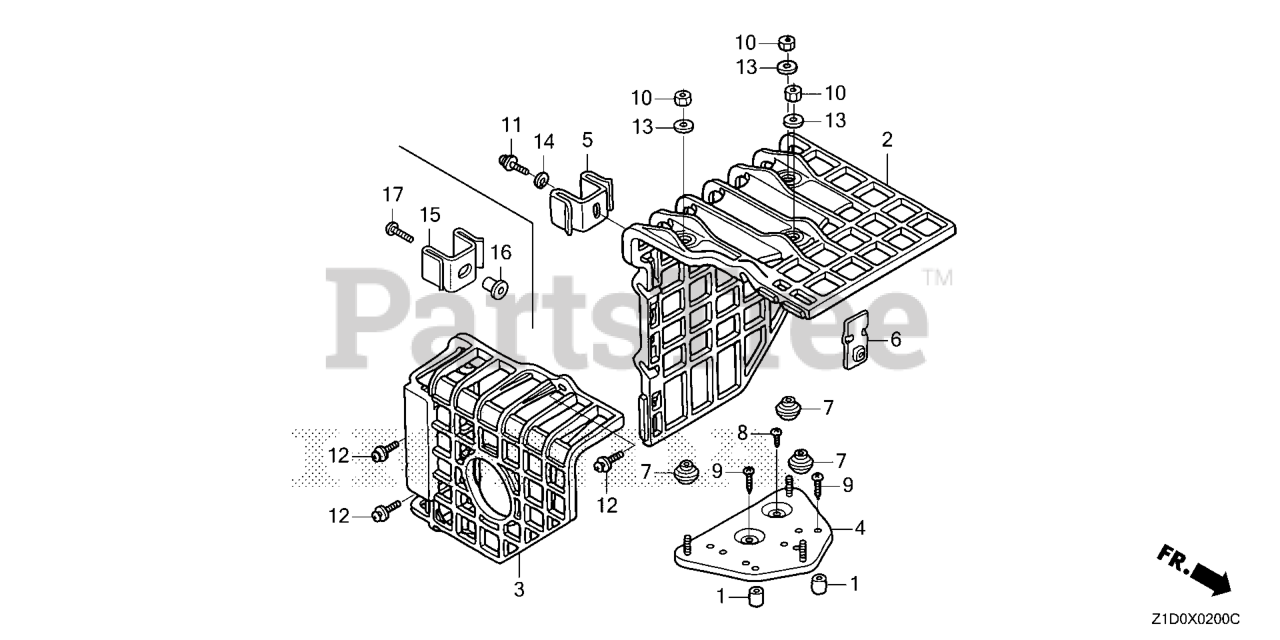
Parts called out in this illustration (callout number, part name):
1	COLLAR, AIR CLEANER HOUSING
2	COVER, MUFFLER
3	COVER, RR. MUFFLER
4	BASE, MUFFLER COVER
7	SPACER, MUFFLER COVER
8	SCREW, TAPPING (5X8)
9	SCREW, TAPPING (5X25)
10	NUT, HEX. (5MM)
12	SCREW-WASHER (6X20)
13	WASHER, PLAIN (5MM)
15	STAY, MUFFLER COVER
16	COLLAR, FAN COVER (Honda Code 5580527). (N/A: SEE ASSEMBLY)
17	SCREW, TAPPING (6X25)
